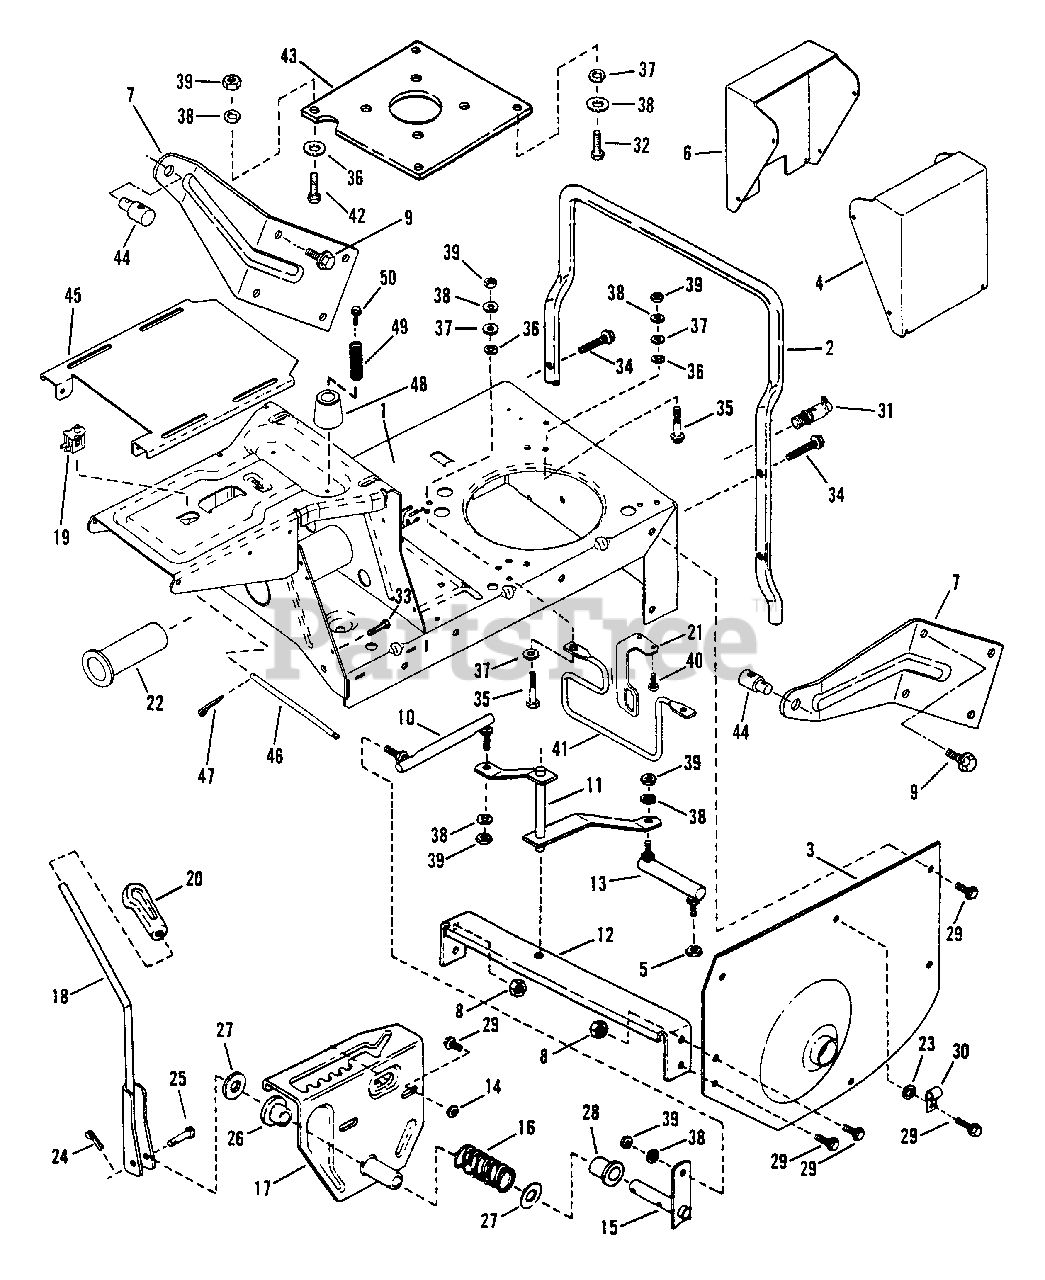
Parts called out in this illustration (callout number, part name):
1	CASE, Main, Units 3314K
2	BUMPER, Rear
3	FENDER, Left Hand
4	COVER, Battery
5	NUT, 5/16-24 Hex Flange Lock
6	COVER, Switch
7	WING, Rear
8	NUT, 5/16-18 Hex Flange Lock
9	SCREW, 5/16-18 x 3/4" Self-Tapping
10	LINK, Shift (Long)
11	ARM, Shift
12	BRACE, Cross
13	LINK, Shift (Short)
14	NUT, 5/16-18 Hex
15	ARM, Shift Handle
16	SPRING, Shift Handle
17	DETENT, Shift
18	HANDLE, Shift
19	SWITCH, Seat
20	KNOB, Shift Handle
21	BRACKET, Switch
22	BUSHING, Pilot
23	WASHER, 5/16 Internal Tooth Lock
24	PIN, 3/32 x 3/4" Cotter
25	PIN, 1/4 x 1-3/4" Tapered Clevis
26	BUSHING, Nylon
27	WASHER, Thrust
28	BUSHING, Nylon
29	SCREW, 5/16-18 x 5/8" Self-Tapping
30	CLIP, Wire
31	DRAIN, Oil (1/4 Turn)
32	SCREW
33	FASTENER, 1/4 x 3/4 Ratchet
34	SCREW, 5/16-18 x 1-1/2" Self-Tapping
35	SCREW, 5/16-24 x 1-3/4" Hex Head Cap
36	RETAINER, 5/16 Bolt
37	WASHER, 5/16" Flat
38	WASHER, 5/16" Split Lock
39	NUT, 5/16-24 Hex
40	SCREW, Self Tap, #10 x 1/4
41	GUIDE, Belt
42	SCREW, 5/16-24 x 1" Hex Head Cap
43	PLATE, Engine
44	SWIVEL
45	PLATE, Seat
46	PIN, Hinge
47	PIN, 1/16 x 3/4" Cotter
48	CUSHION
49	SPRING, Seat O.P.C.
50	SCREW, Self Tapping 1/4-20 x 1/2
